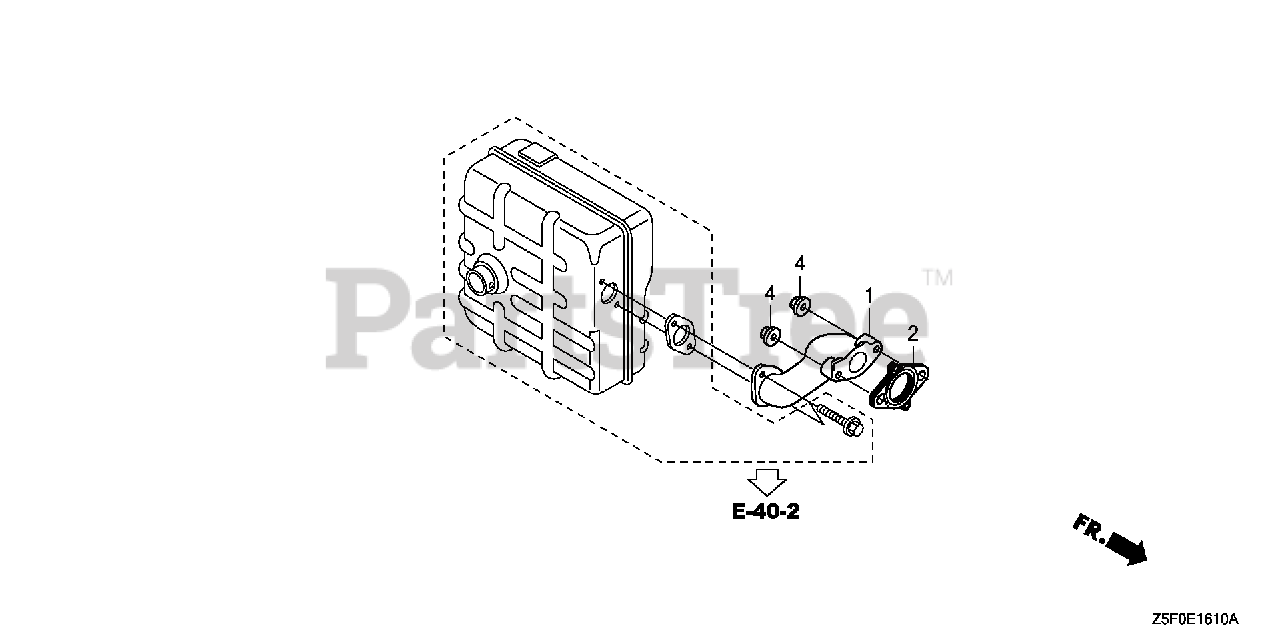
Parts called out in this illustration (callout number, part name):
2	GASKET, EX. PIPE
3	ARRESTER, SPARK
4	NUT, FLANGE (8MM)
5	SCREW, TAPPING (4X8)
